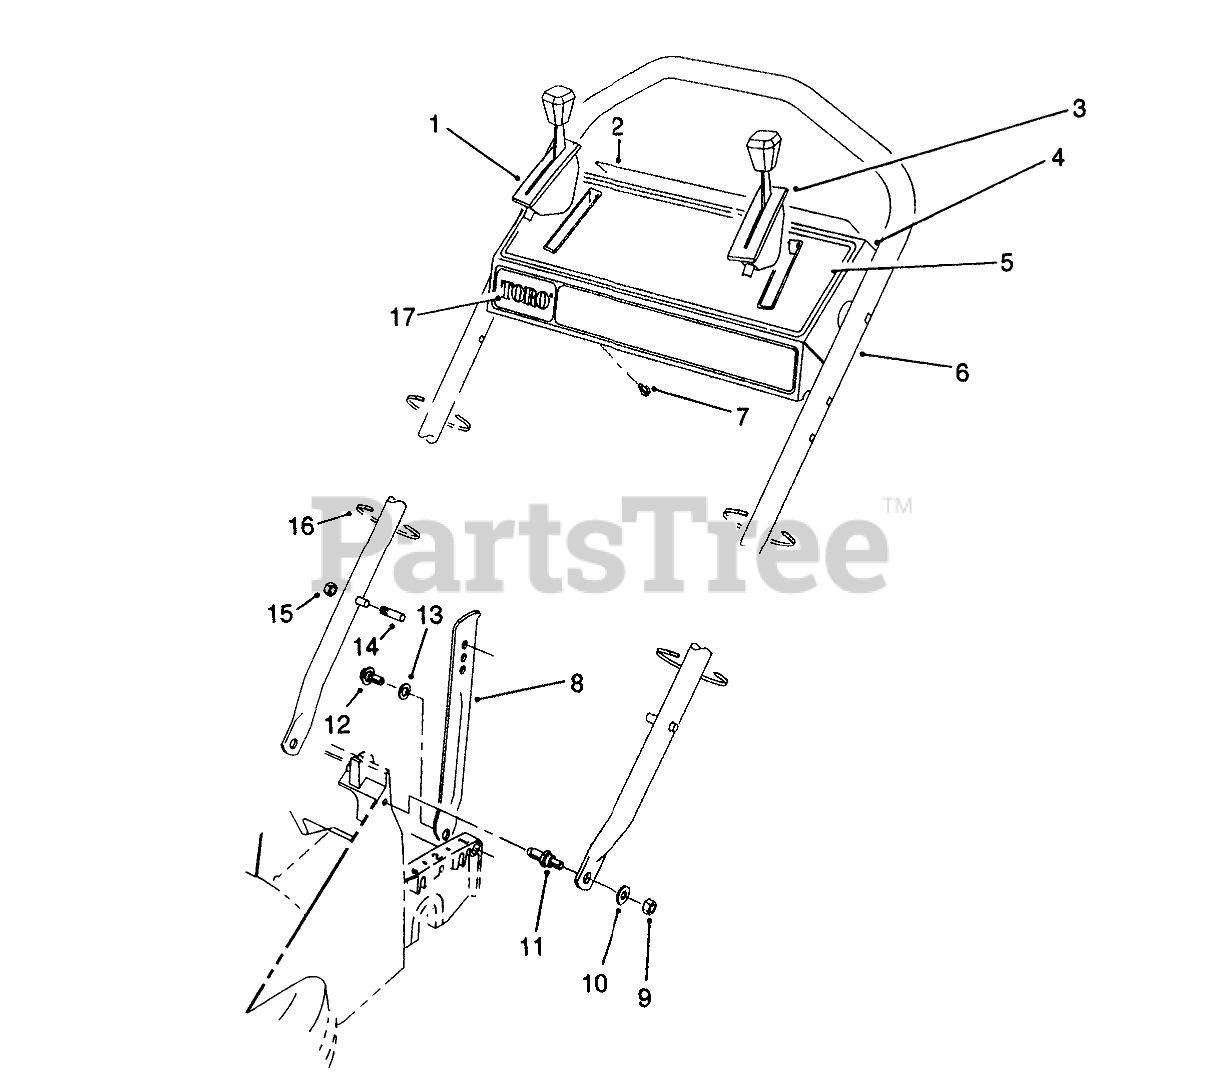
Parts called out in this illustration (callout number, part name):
1	Control-Ground Speed
2	DECAL-PANEL, DANGER
3	Control-Throttle Bend Type #1 Sheath Lg. 43-3/4" Wire Lg. 2-5/8"
4	Panel-Control (Incl. Ref. #2, 5 & 16)
5	DECAL - INSTRUCTION
6	HANDLE
7	SCREW-HWHTF
8	HANDLE LATCH
9	NUT-LOCK, NI
10	WASHER-PLAIN
11	SCREW - SHOULDER STUD
12	SCREW-SHOULDER
13	NYLON WASHER
14	HANDLE PIN
15	NUT-LOCK, NI
16	TIE-CABLE
17	DECAL - TORO PANEL
